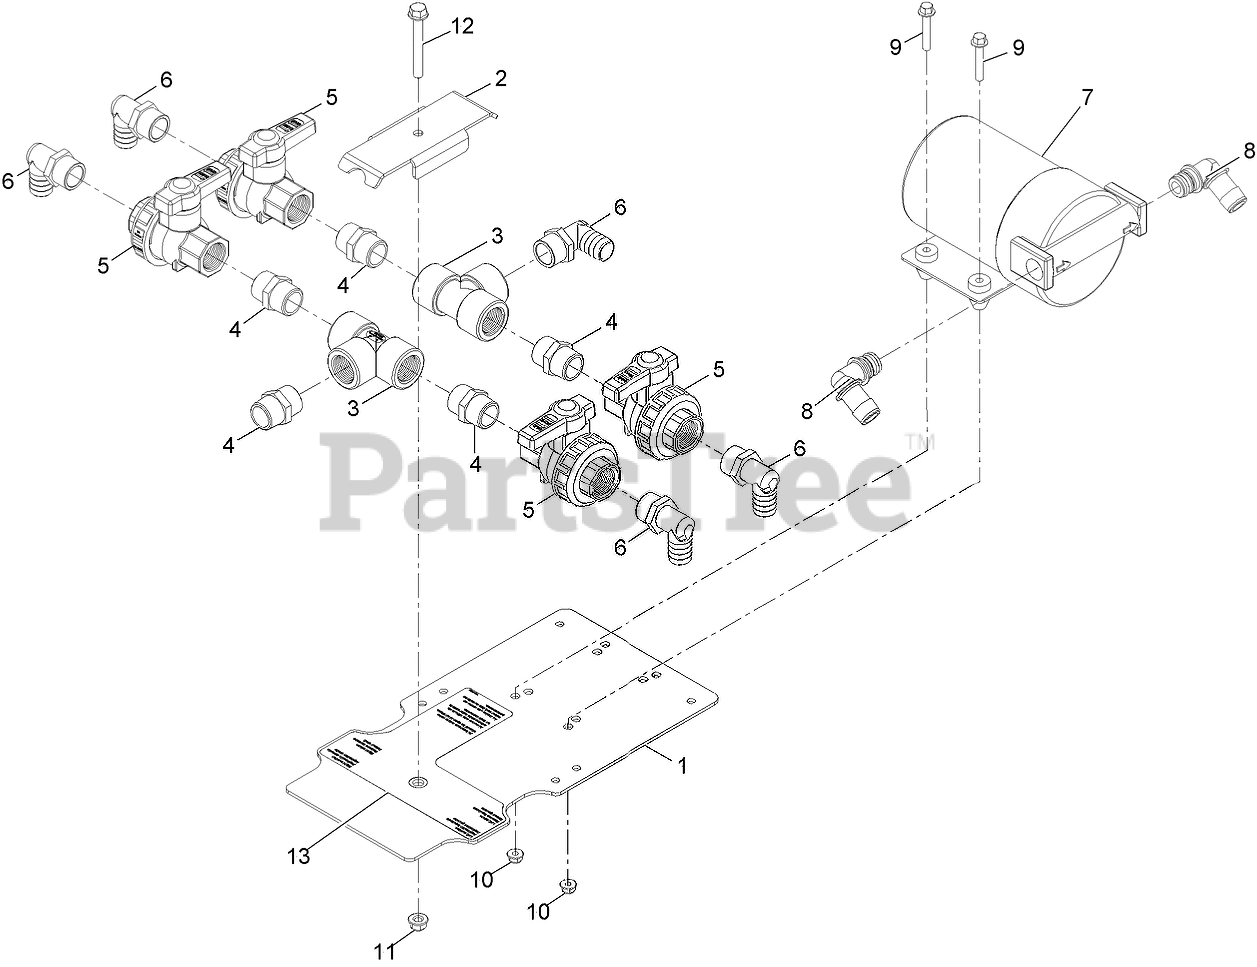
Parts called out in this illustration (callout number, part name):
1	MOUNT-PLATE, LIQUID VALVE
2	PLATE-CLAMP, LIQUID VALVE
3	FITTING-TEE
4	FITTING-NIPPLE
5	VALVE-UNION, 3/4
6	FITTING-ELBOW, 90
7	7.0 REMCO PUMP
8	FITTING-ELBOW
9	Screw-HHF
10	Nut-Hex Flange
11	Nut-Hex Flange
12	Screw-HHF
13	DECAL-VALVE, TANK
